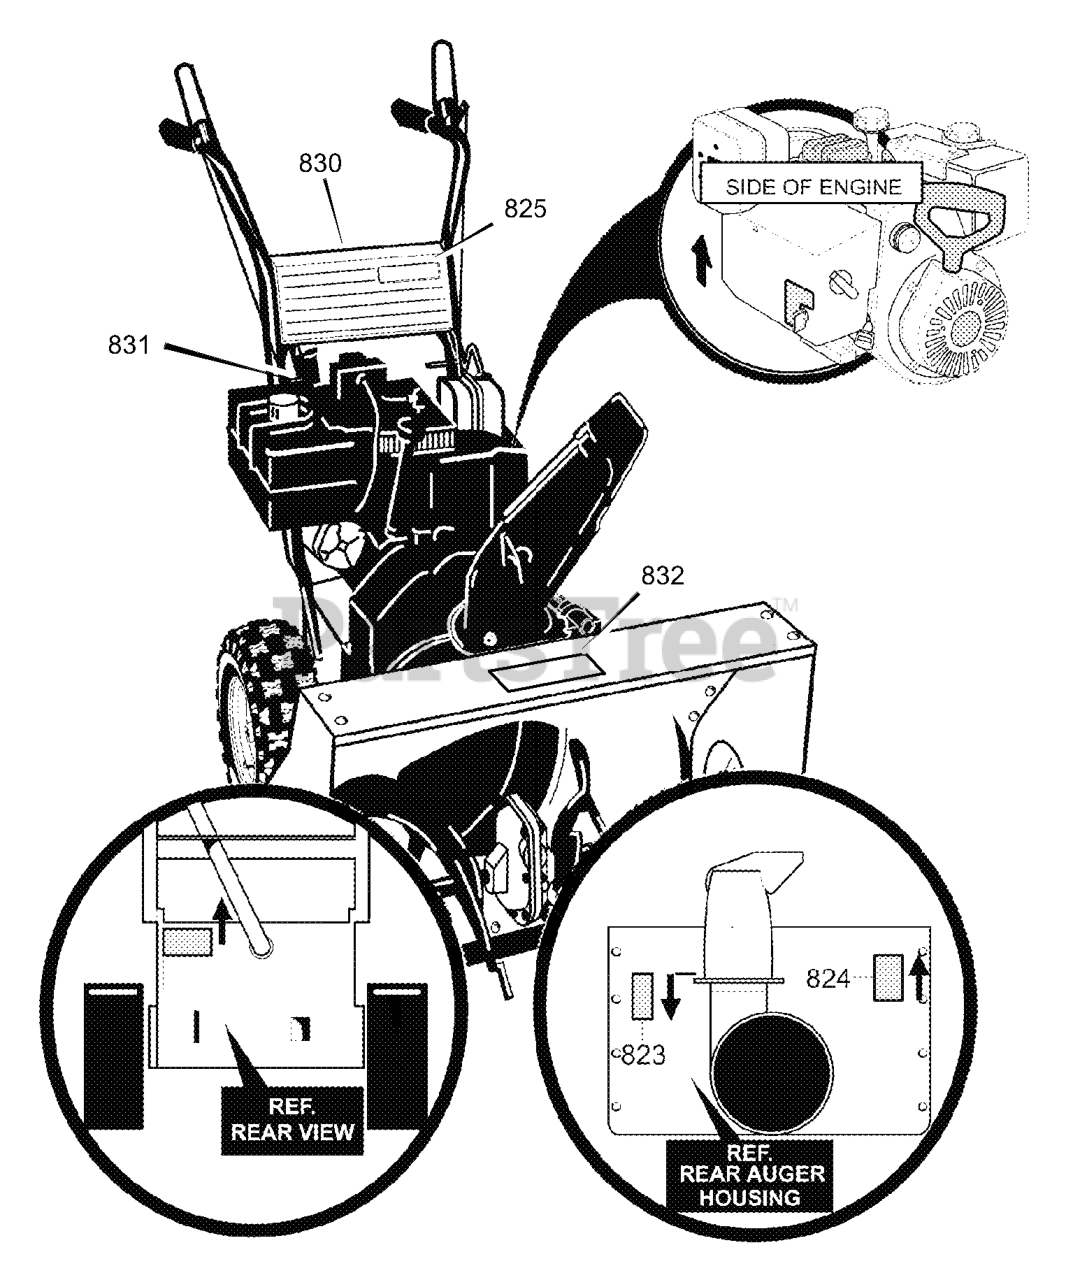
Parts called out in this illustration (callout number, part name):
823	DECAL, HAND DANGER CHUTE
824	DECAL, DANGER FOOT
825	DECAL, SELECT MURRAY
830	DECAL, DRIVE TRACTION AUGER
831	DECAL, SELECTOR GEAR
832	DECAL, 5/22
